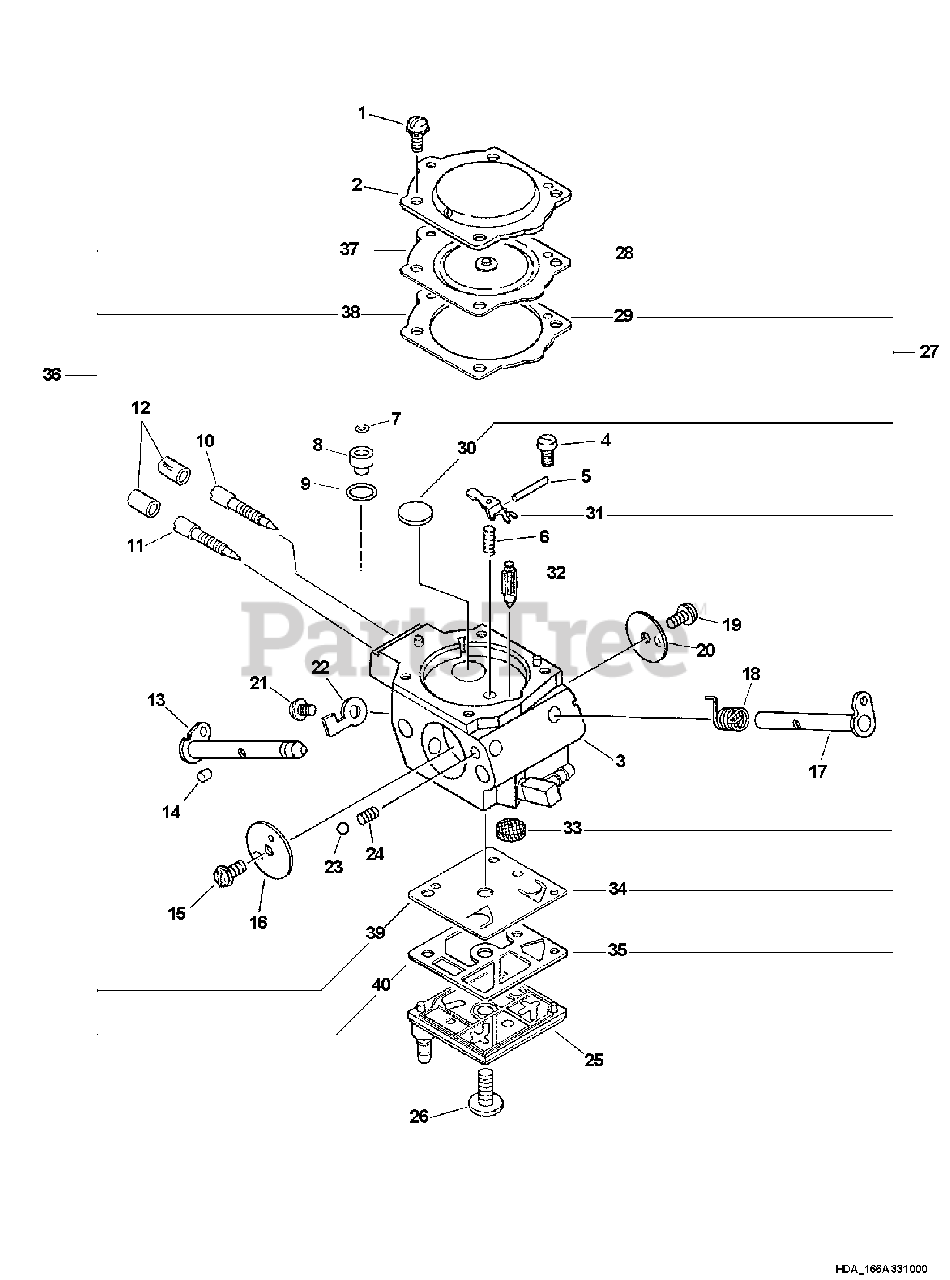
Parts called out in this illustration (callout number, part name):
2	COVER, METERING
3	BODY, CARBURETOR
4	SCREW, METERING LEVER PIN
5	PIN, METERING LEVER
6	SPRING, METERING LEVER
7	RING, RETAINING
8	JET, MAIN - 42
10	NEEDLE - MIXTURE
11	NEEDLE - HIGH SPEED
12	CAP, LIMITER
13	SHAFT, CHOKE
16	VALVE, CHOKE
17	SHAFT, THROTTLE
18	SPRING, THROTTLE RETURN
20	VALVE, THROTTLE
22	STOP, THROTTLE
23	BALL, CHOKE
25	COVER, PUMP
26	SCREW, PUMP COVER
27	REPAIR KIT
28	DIAPHRAGM, METERING
29	GASKET, DIAPHRAGM
30	PLUG, WELCH
31	LEVER, METERING
32	VALVE, INLET NEEDLE
33	STRAINER
34	DIAPHRAGM, PUMP
35	GASKET, PUMP
36	DIAPHRAGM/GASKET KIT
37	DIAPHRAGM, METERING
38	GASKET, DIAPHRAGM
39	DIAPHRAGM, PUMP
40	GASKET, PUMP
